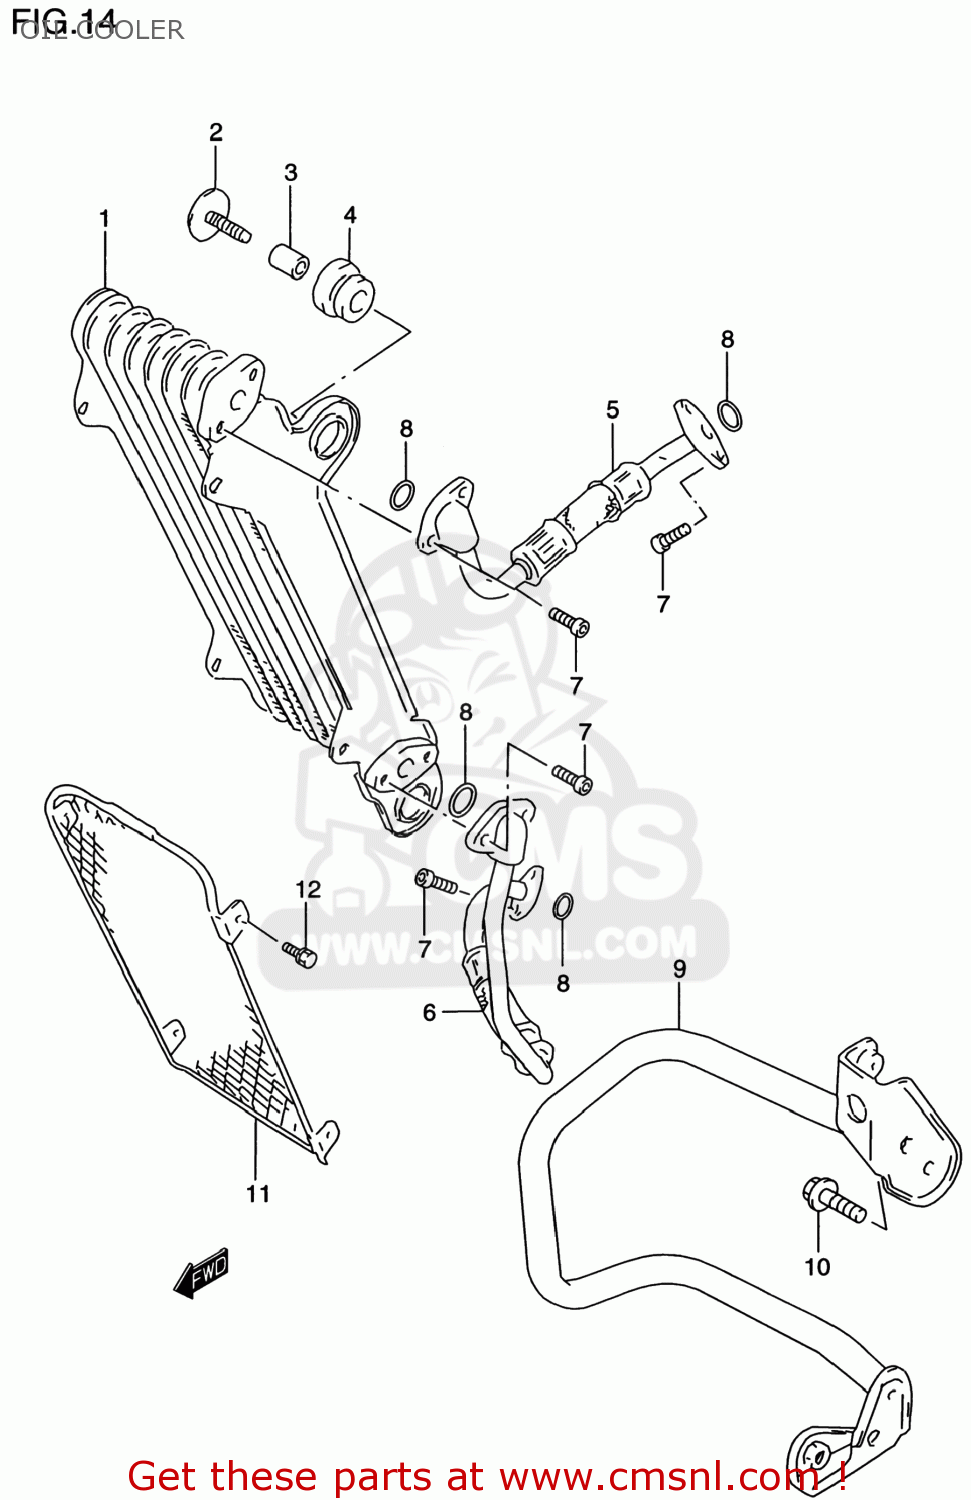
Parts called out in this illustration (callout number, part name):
1	COOLER ASSY,OIL
2	BOLT 8X28
3	SPACER,OIL COOLER
4	CUSHION,OIL COOLER
5	HOSE,OIL COOLER UPR
6	HOSE,OIL COOLER LWR
7	BOLT,OIL FILLE
8	O RING(D:2.4,ID:12.3)
9	GUARD,OIL COOLER
10	BOLT
11	BUMPER,OIL COOLER
12	BOLT
